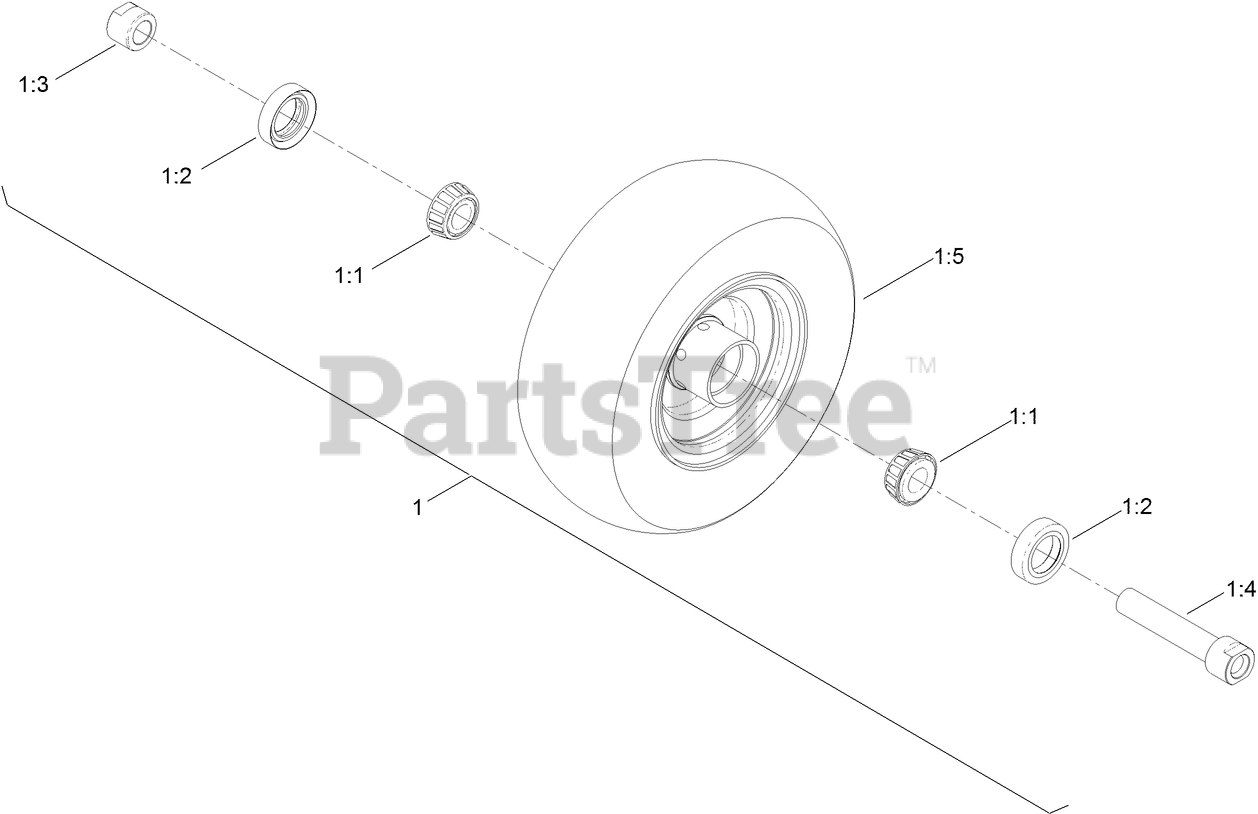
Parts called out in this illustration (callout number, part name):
1	WHEEL AND BEARING ASM
1:1	BEARING-CONE, TAPER
1:2	SEAL-CASTER
1:3	SPACER-NUT
1:4	CASTER AXLE ASM
1:5	WHEEL AND TIRE ASM
